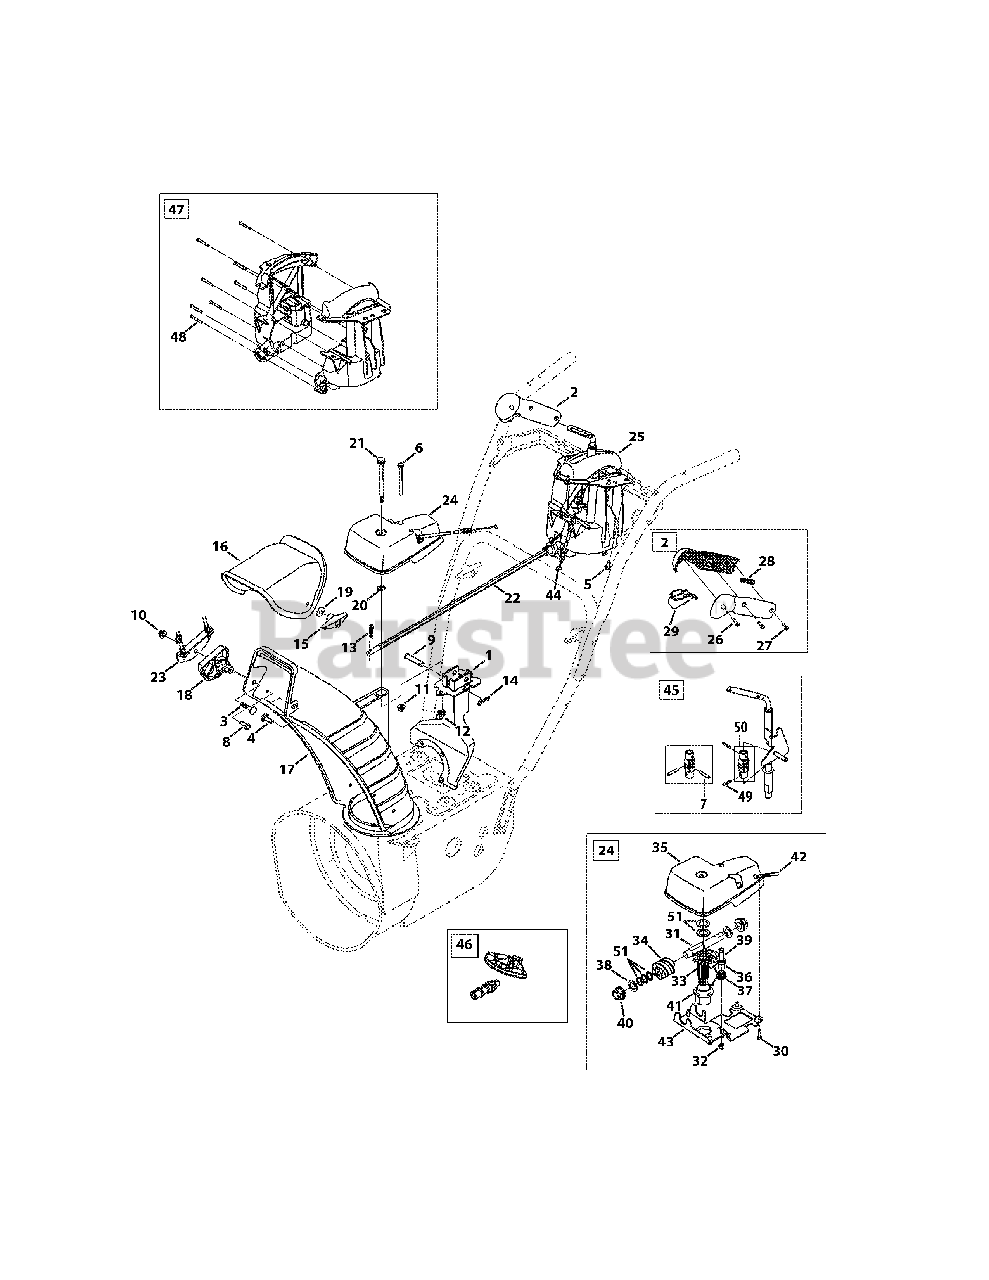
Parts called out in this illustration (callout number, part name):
1	Chute Support Bracket
2	Handle Assembly
3	Bolt, Carriage, 5/16-18 x 1.50
4	Bolt, Carrier, 5/16-18 x 1.00
5	Screw, HL, 1/4-15 x 0.50
6	Hex Head Screw, 1/4-20 x 3.00
7	Pin, Roll
8	Screw, HL, 1/4-15 x 0.750
9	Clevis Pin, 3/8 x 1.87
10	Nut, Flangelock, 5/16-18
11	Nut, Flangelock, 1/4-20
12	Wing Nut, 1/4-20
13	Internal Cotter Pin
14	Bow-Tie Cotter Pin
15	Wing Knob, 5/16-18
16	Chute, Upper
17	Chute, Lower
18	Cable Guide, Chute Tilt
19	Washer, Flat, .349 x .879
20	Washer, Flat, .25 x .630
21	Screw, Shoulder, .312 x 3.5 x 1/4-20
22	Chute Rod, 3/8 Hex
23	Cable Bracket
24	Gearbox Assembly, Chute Rotation
25	Chute Control, 4-Way
26	Screw, #8 x 1.00
27	Screw, 8-32 x .750
28	Joystick Plug
29	Joystick Trigger
30	Screw, 12-16 x .75
32	Hexlock Nut, 1/4-28
34	Worm
35	Gear Cover
37	Torsion Spring, .721 ID x .394
38	Washer, Flat, .625 x 1.0 x .067
39	Screw, Shoulder, .340 x .950 x 1/4-28
40	Hex Bearing
41	Flange Bearing
44	4-Way Cable
45	Shift Assembly
46	Gear Set Assembly
47	Handle Housing Assembly
48	Screw, #8-18 x 1.250
50	Block, Asm Joint
51	Shim Washer, .632 x 1.00 x .010
